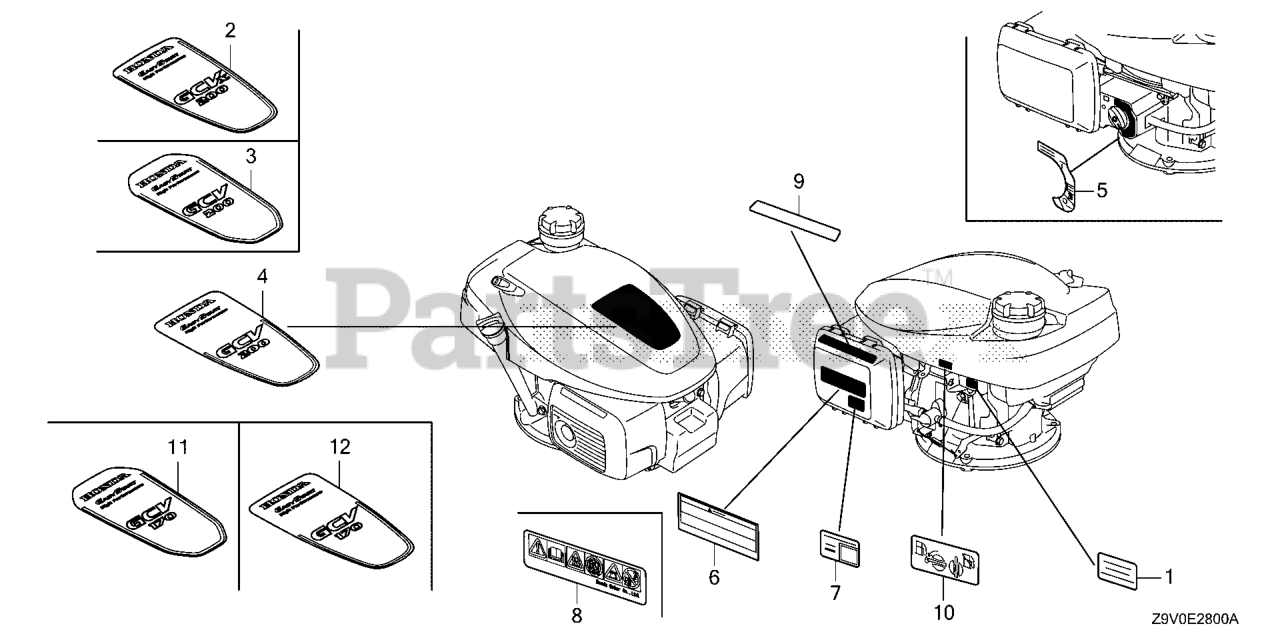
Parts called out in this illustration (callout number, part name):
1	LABEL, WARNING (NOT CERTIFIED FOR SALE)
6	MARK, OPERATOR CAUTION
10	MARK, FUEL PETCOCK
12	MARK, TOP COVER
